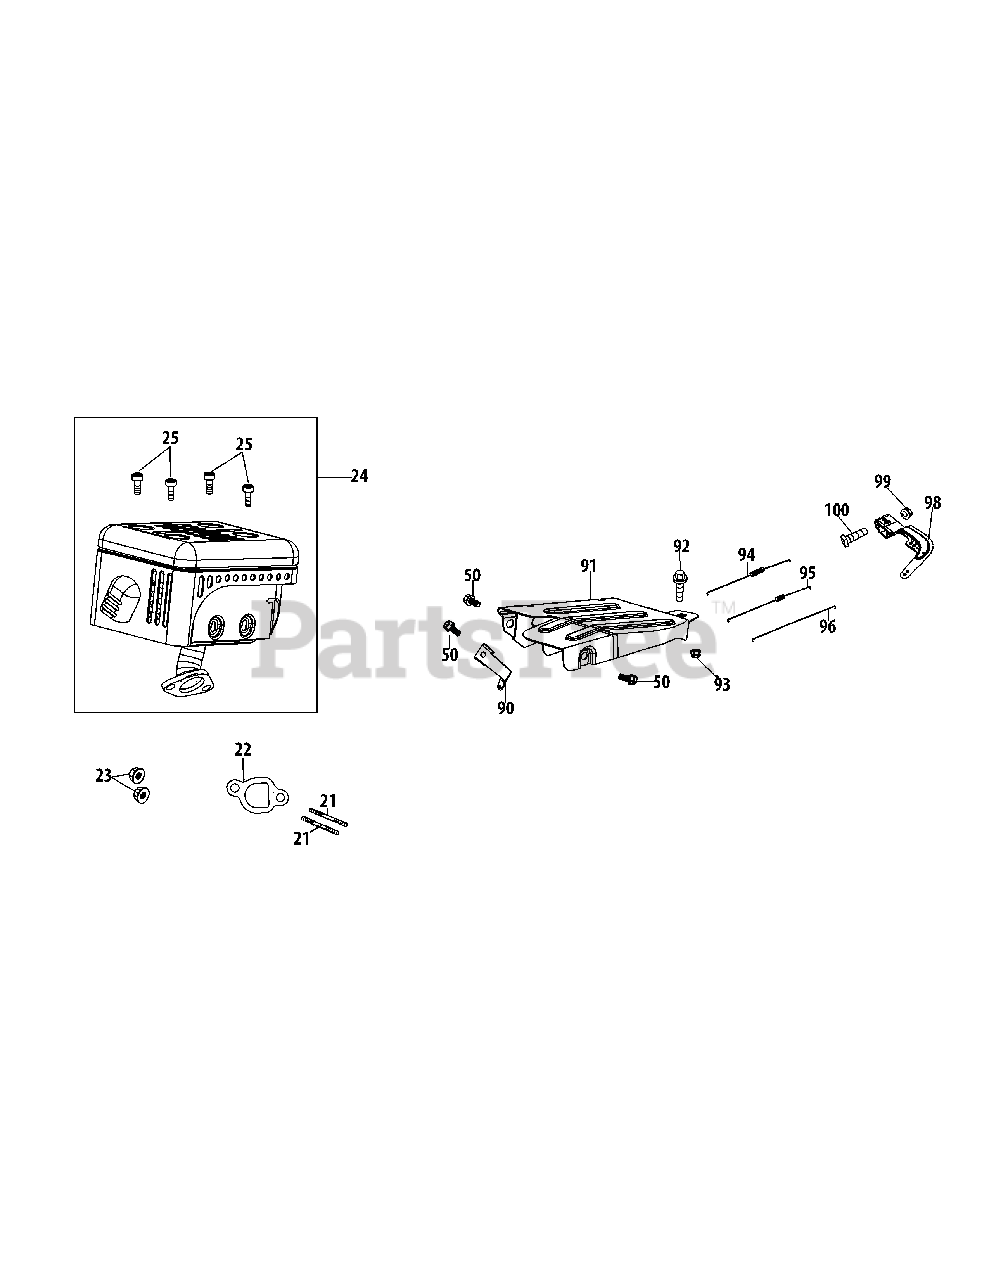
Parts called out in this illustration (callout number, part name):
21	Muffler Stud
21	Muffler Stud Assembly
22	Muffler Gasket
24	Muffler Assembly
25	Bolt
50	Bolt:M6X12 Zinc
90	Governor Spring Bracket
91	Governor Shield
92	Bolt- Special 8 Mm Head
94	Governor Spring
95	Throttle Return Spring
96	Governor Rod
98	Governor Arm Bracket
99	Flange Nut M6
100	Governor Arm Bolt M6X21
